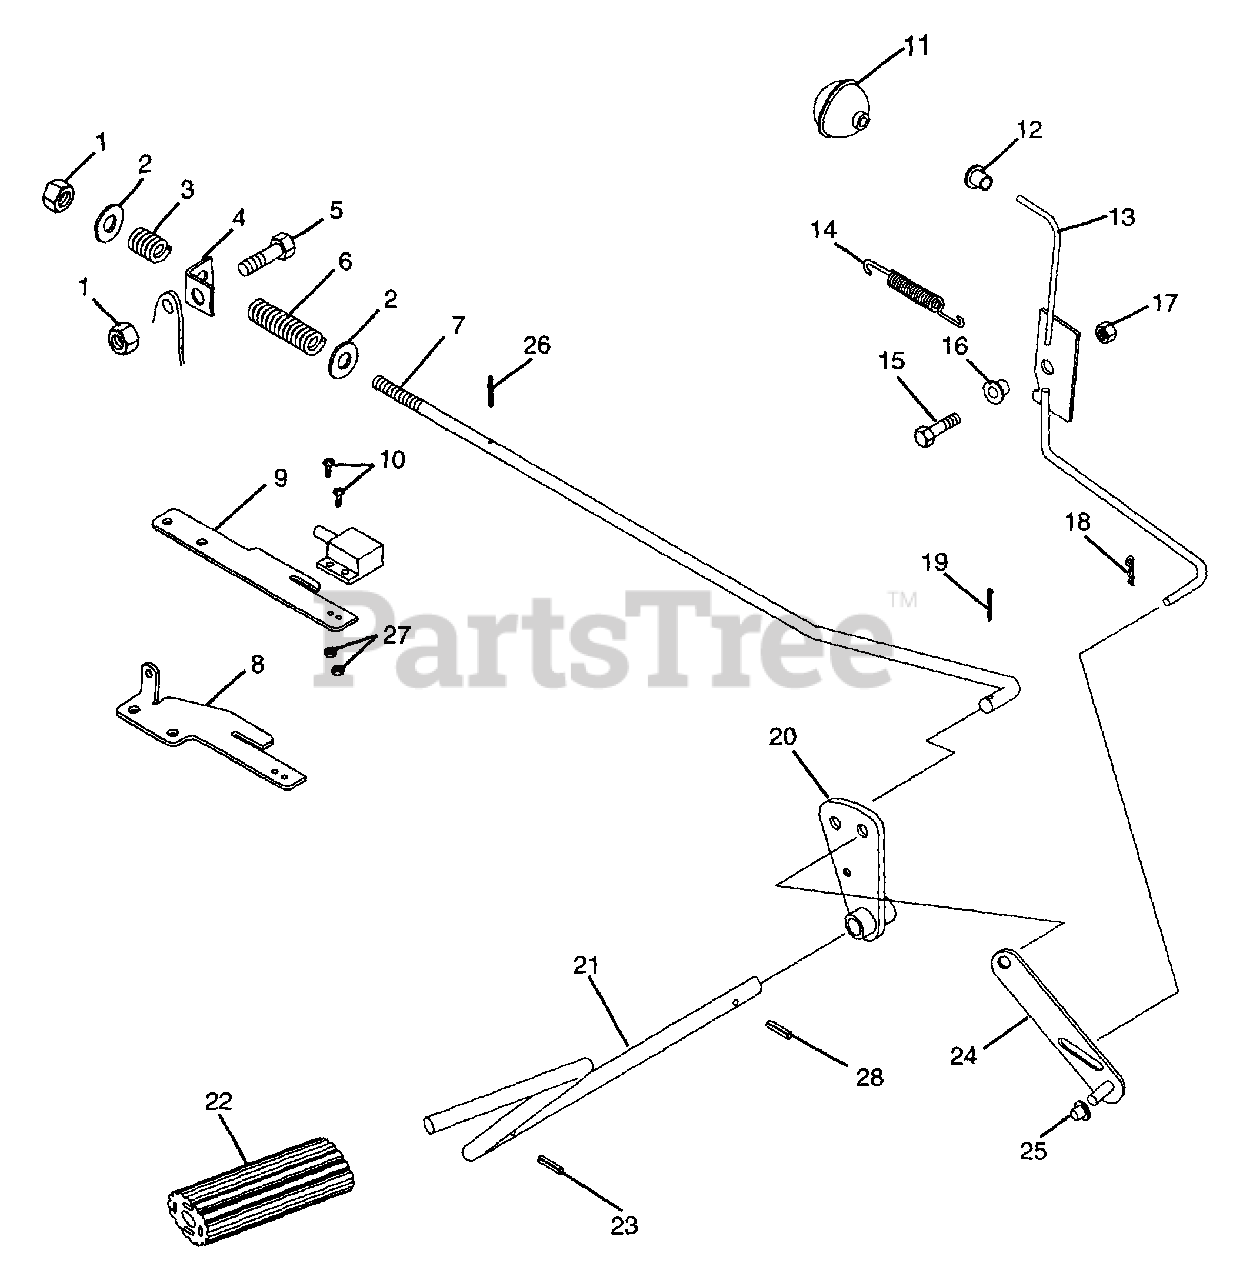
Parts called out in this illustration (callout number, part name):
1	NUT-LK-CTR .375-16 GR A PL
2	WSHR-FL-STL.406X.812X.065PL
3	SG-COMP .125X.78X1.00 YWZ
4	BRACKET
5	BLT-HEX .38-16X.75 PL GR5
6	SG-COMP .048X.59X2.06 WLD9
7	BRAKE ROD
8	BRAKE GUIDE
9	BRAKE GUIDE
10	SCR-MCH 10-24X.62 P/HD
11	PUSH/PULL CONTROL KNOB
12	SNAP BUSHING-.437
13	PARKING BRAKE LEVER
14	SG-TENS .051X.44X4.38 WLD 7.5
15	BLT-HEX .31-18X.75 PL GR5
16	BSHG, FLG .325X.499X.26X.88
17	NUT-LK .312-18 GR A PL
18	PIN-HAIR INT .08X.18X1.18
19	PIN-COTR .09X.75 PL
20	ARM & HUB
22	COVER- PEDAL
23	PIN-GRV .188X1.25 TP A
24	PIVOT PLATE
25	NUT-PUSH .312 DIA. PAL
26	PIN-ROLL .125X.75
27	NUT-LK 10-24 NY PL
28	PIN-ROLL .188X1.25
